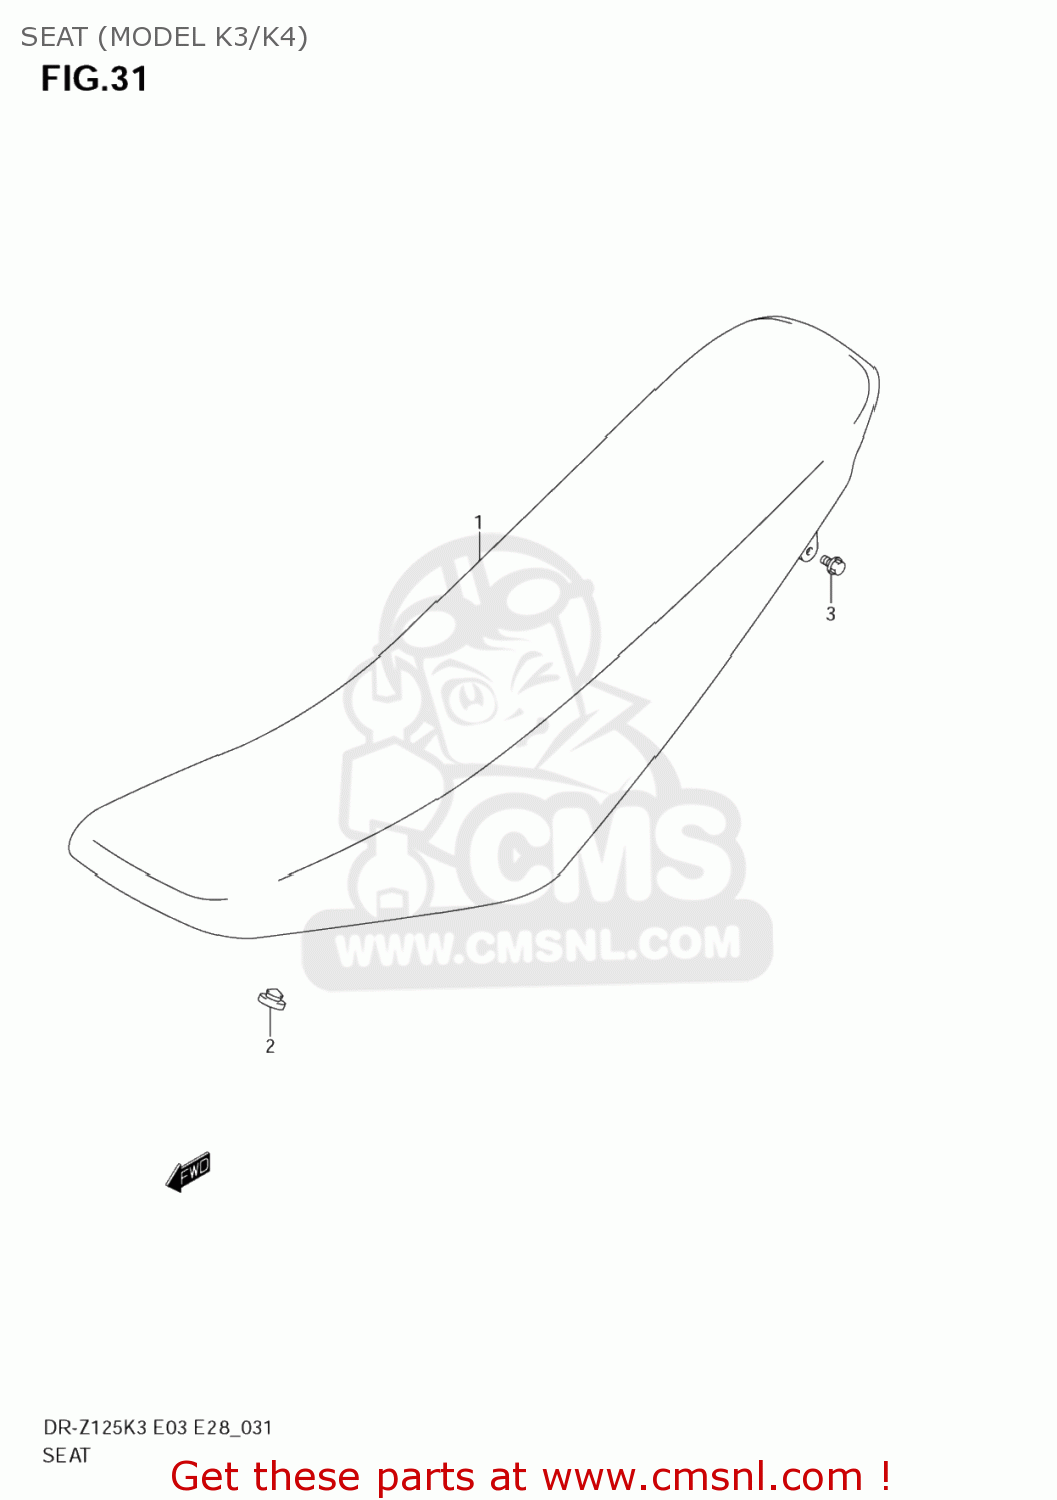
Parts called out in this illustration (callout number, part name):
1	SEAT ASSY
2	CUSHION
3	BOLT
